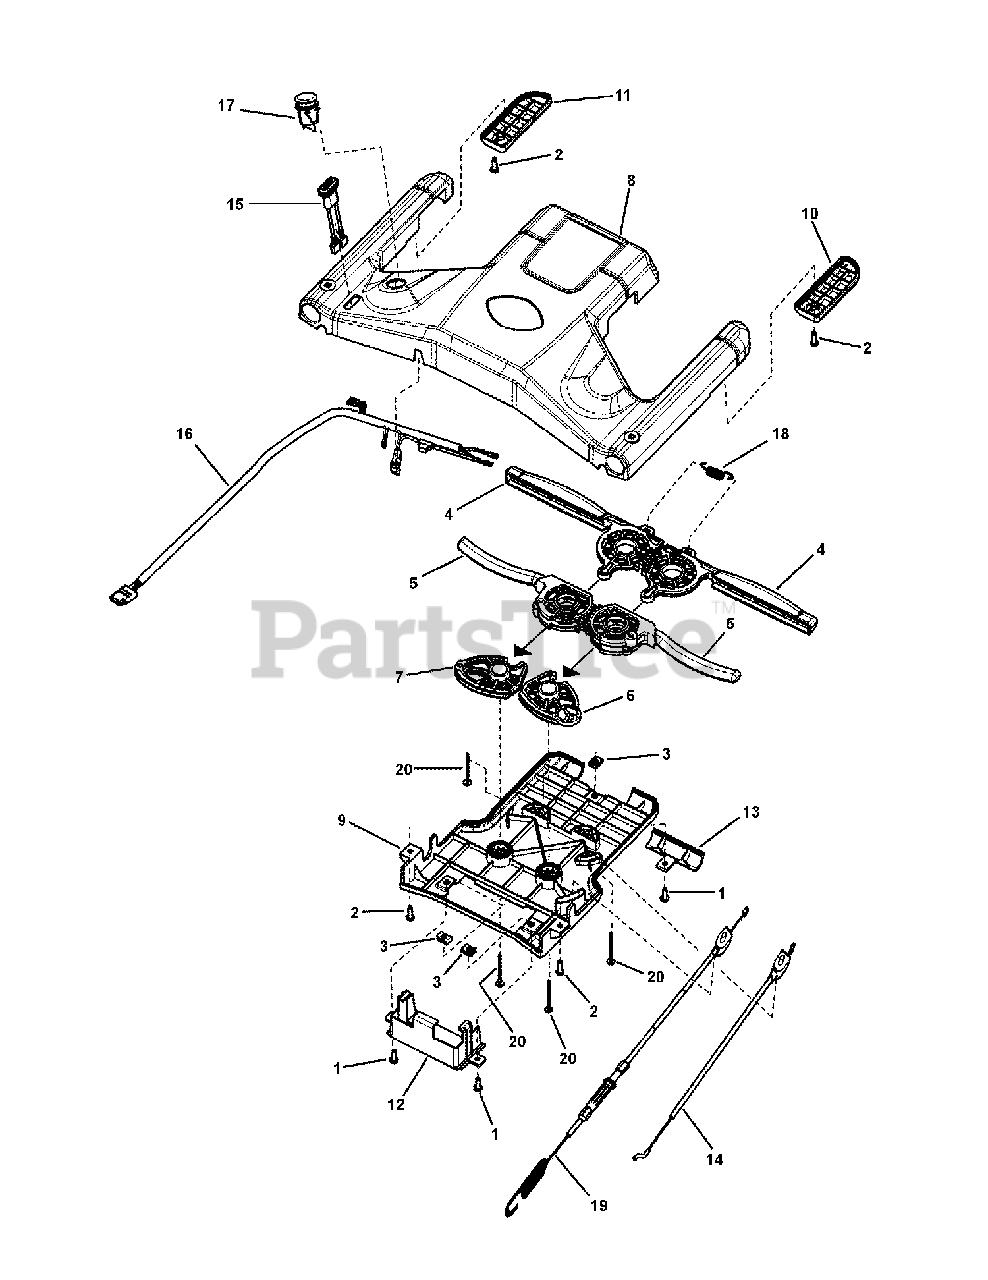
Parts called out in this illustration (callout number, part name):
1	SCREW, #10-24 x 5/8" Hex Washer Self-Tap, GR 5 BZ
2	SCREW, #10-16 x 3/4" Pan Head Self-Tap Combo, BZ
3	NUT, #10-24 Speed Retainer w/extrusion
4	LEVER, Drive Control
5	LEVER, OPC, Control
6	CAM, Drive, LH
7	CAM, Drive, RH
8	CONTROL PANEL, Top, MY Mower
9	CONTROL PANEL, Bottom, MY Mower
10	PANEL, Bottom Control, WBM, RH
11	PANEL, Bottom Control, WBM, LH
12	ACCESS DOOR, Battery Control Panel, WBM
13	PANEL, Access, Maintenance Reminder
14	CABLE, OPC, NXT
15	HOUSING, Bridge Disconnect
16	HARNESS, Electric Start, NXT
17	SWITCH, Push Button Start
18	SPRING, Tension, Drive Control
19	CABLE, Control, NXT
20	SCREW, #10-16 x 2" Hi-Lo Cross Pan Head
